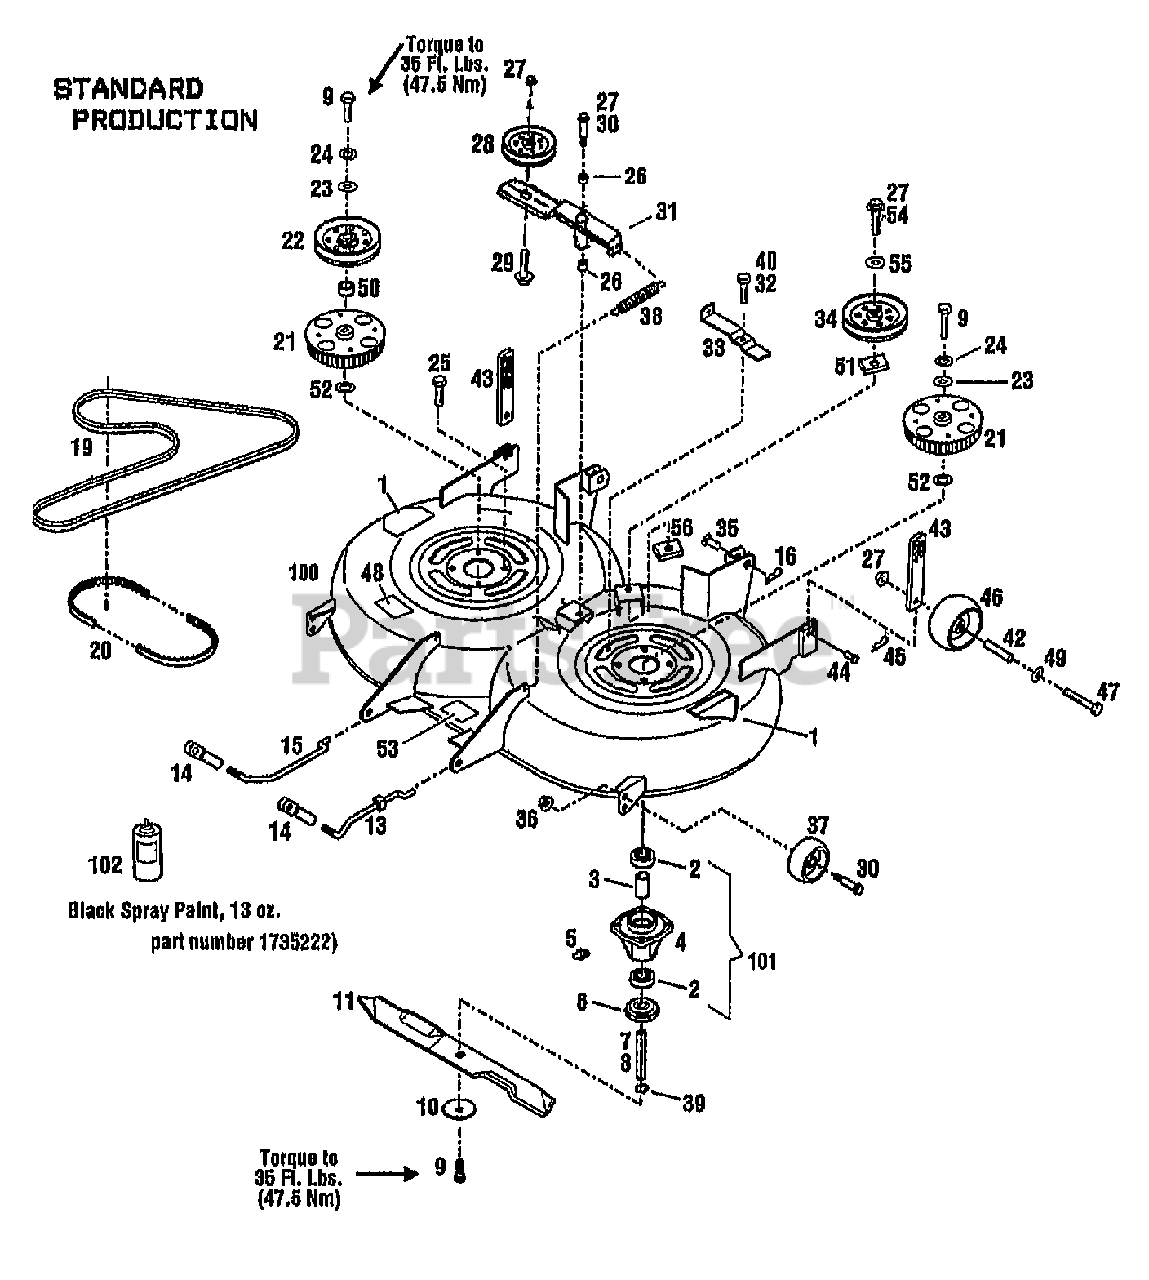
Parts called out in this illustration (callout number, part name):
1	DECAL-OPEI CAUTION
2	BEARING-BALL
4	HOUSING-SPINDLE
5	FITTING-GREASE 1/4-28X2.00
6	SPACER-BLADE
7	SHAFT-SPINDLE MED. H/T
8	SPINDLE-SHAFT LONG H/T {14094}
9	SCR-HH 1/2-14X1.00
10	WASHER-BELLEVILLE
11	BLADE-MULCHING
13	ROD-LIFT FRONT LH
15	ROD-LIFT FRONT RH
16	PIN-HITCH .125X2.56 ZP
19	BELT-DRIVE PTO
20	BELT-DRIVE 38"
21	SPROCKET-56T GRIVORY
22	ASSM-SHEAVE DRIVE
23	WASHER-1.37X.453X.179 ZP
24	WASHER-LK .438 ZP
25	SCR-HFLK 5/16-18X.75
26	BUSHING-.5X.5 NYLON FLNG
27	NUT-HFLK 3/8-16 ZP
29	SCR-HFLK 3/8-16X1.75 G5ZP
30	SCR-SHLDR 3/8-16
31	ARM-IDLER {14094}
32	SCR-HHC 5/16-18X.75 GR 5 ZP {14094}
33	BRKT-BELT TENSION ADJ
35	PIN-CLEVIS .625X2.25
36	NUT-LOCK 3/8-16
37	WHEEL-GAGE
38	SPRING-EXTENSION
39	RING-RETAINING EXT .694 ID
40	NUT-TOP/LK 5/16-18 ZP
42	SPACER-GAGE WHEEL
43	BAR-GAGE WHEEL ADJ {14094}
44	PIN-CLEVIS .375 X .937 ZP
45	CLIP-HAIRPIN .07 DIA
46	WHEEL-GAGE
47	SCR-HH 3/8-16X3.5 G5 ZP
48	DECAL-BELT DRIVE
49	WASHER-.986X.437X.083 ZP
50	SPACER-1.25X.76X.50 {14094}
51	SPACER .390 X .50 {14094}
52	HARDENED WASHER
53	DECAL-LIFT ROD
54	SCR-HH 3/8-16X2.50 {14094}
55	WASHER-FLAT 3/8 SAE {14094}
56	SPACER-1/4 SPEC F/14094 {14094}
100	DECK-MOWER W/DECALS
101	ASSM-MOWER SPINDLE
102	PAINT-BLACK SPRAY
